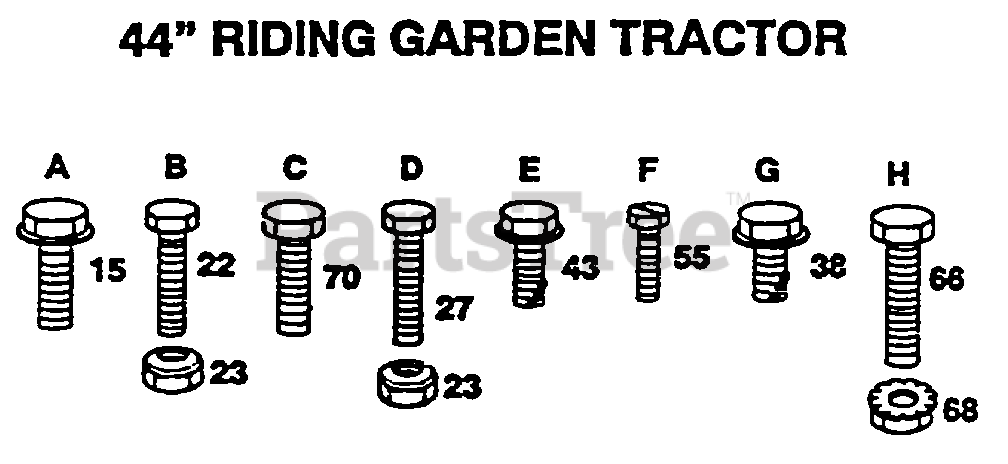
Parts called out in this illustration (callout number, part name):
15	SCREW SPECIAL
22	SCREW
27	BOLT
38	SCREW LT
43	SCREW LT
66	BOLT
68	NUT
70	SCREW
